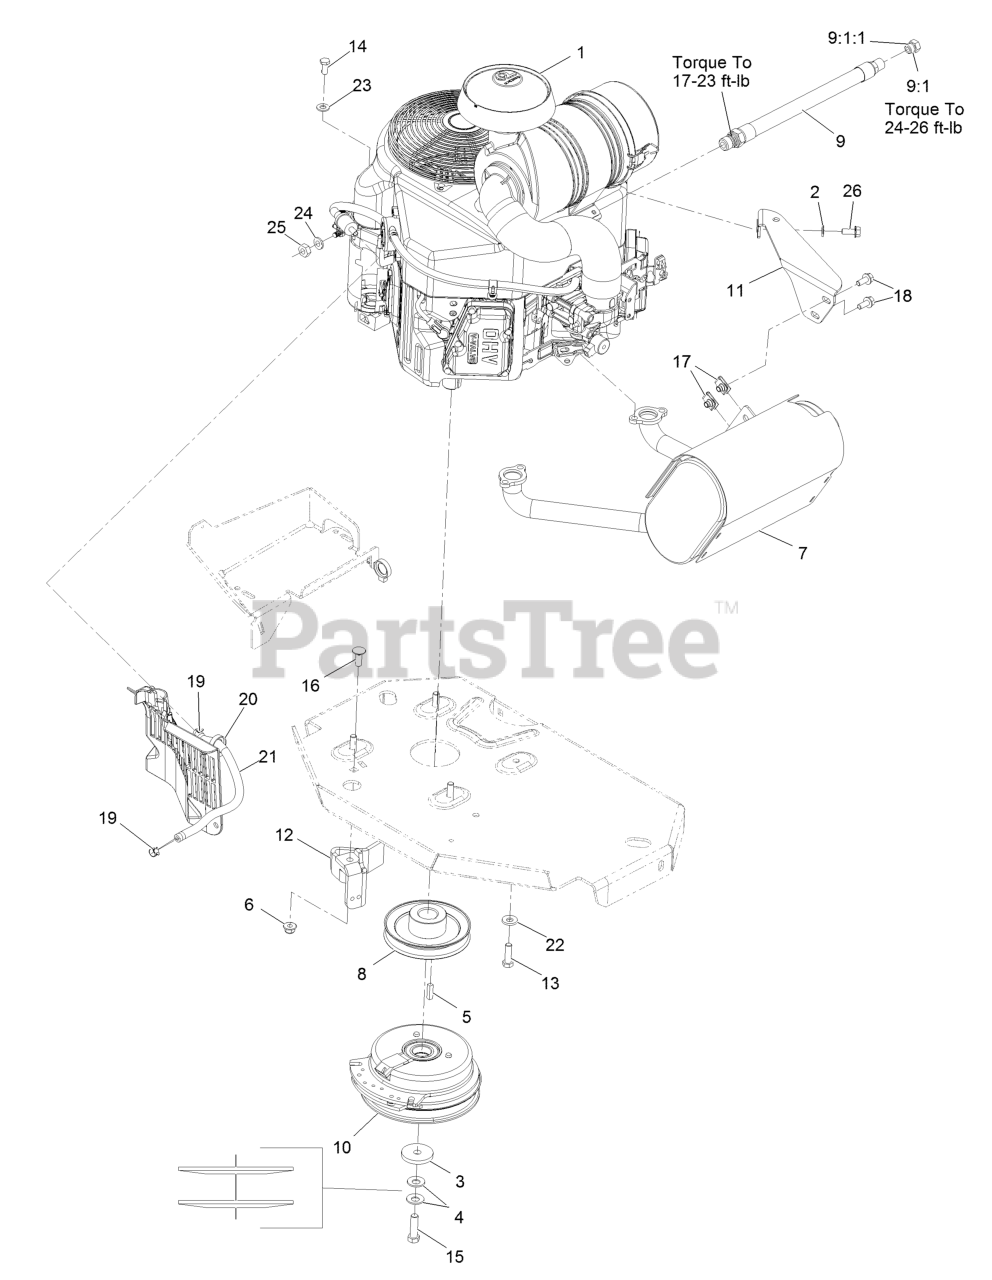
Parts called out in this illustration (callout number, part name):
2	WASHER-SPRING
3	WASHER-CLUTCH
4	WASHER-SPRING
6	NUT-HF, NI
7	MUFFLER
8	SHEAVE-PUMP, DRIVE
9	ENGINE OIL DRAIN HOSE ASM
9:1	PLUG-HH
9:1:1	O-RING
11	BRACKET-MUFFLER
12	CLUTCH-ANCHOR
13	SCREW-HH
14	SCREW-HH
15	SCREW-HH 7/16-20 X 1 1/2 W/LOCTITE
16	SCREW-CARR
18	SCREW-HHF
19	CLAMP-HOSE
20	CLAMP-HOSE
21	HOSE-FUEL
22	WASHER-BELLEVILLE
23	WASHER-PLAIN
24	WASHER-FLAT
25	NUT-HEX
26	SCREW-HHF
